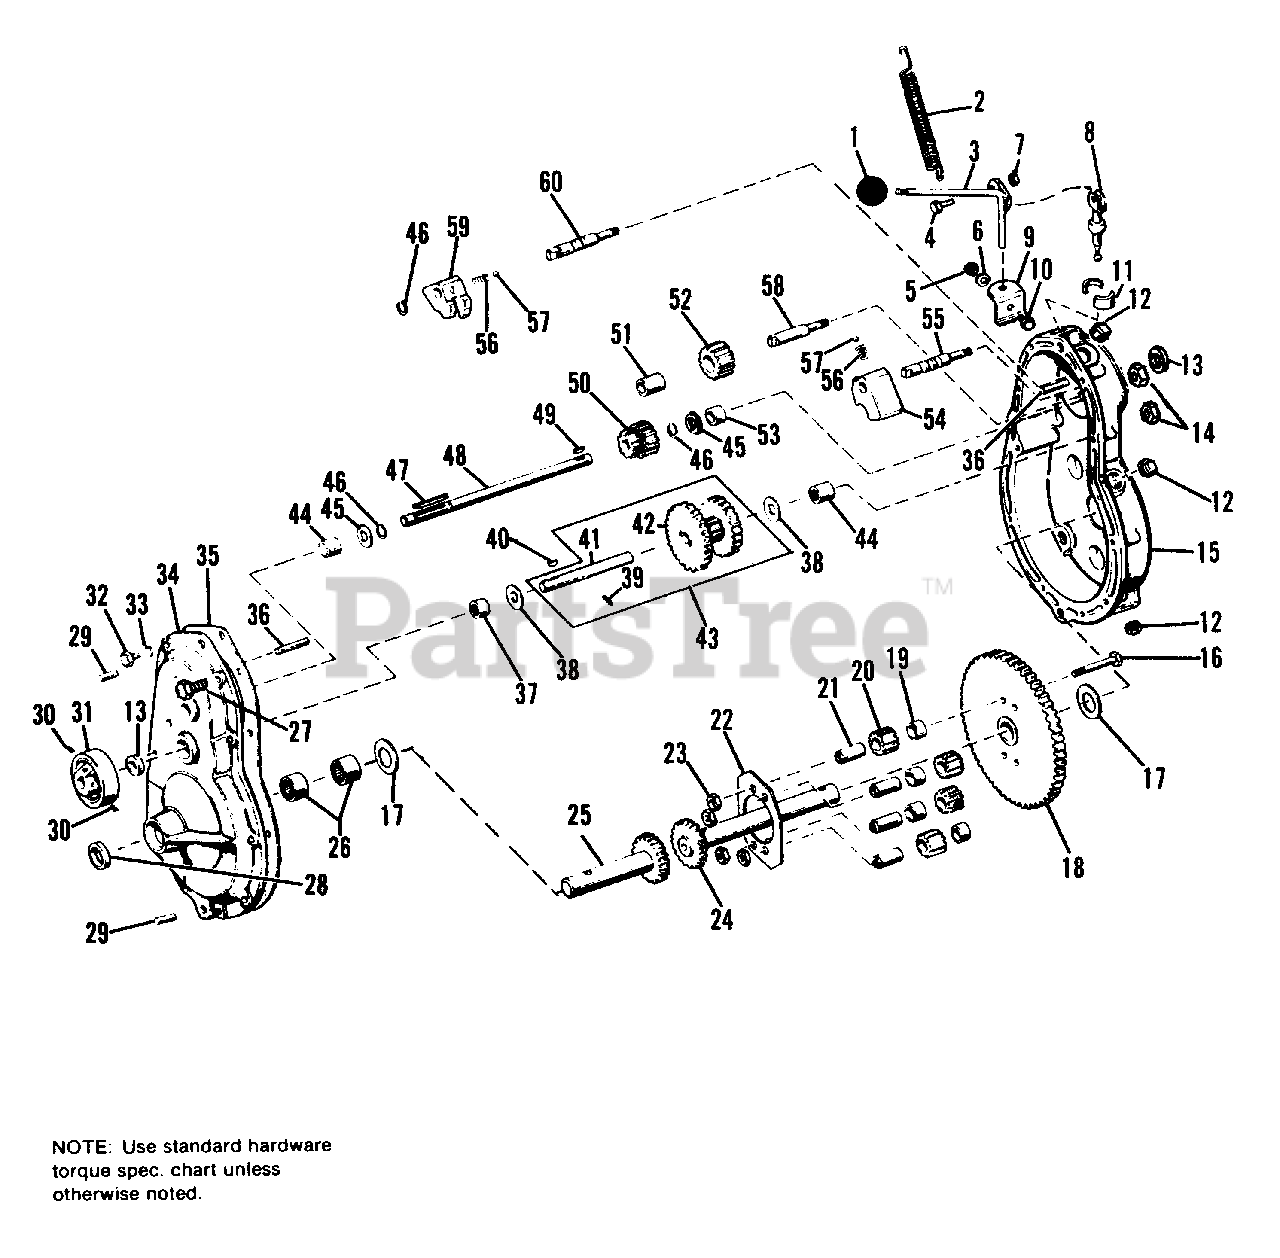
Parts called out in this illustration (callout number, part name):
2	SPRING
3	LEVER ASSY., Shift
4	CAPSCREW, Hex Hd., 1/4-20 x 3/4
5	NUT, Hex, Full, 5/16-18
6	LOCKWASHER, 5/16
7	LOCKNUT, Hex, 1/4-20
8	ROD ASSY., Shift
9	PIVOT, Shift Lever
10	CAPSCREW, Hex Hd., 5/16-18 x 7/8
11	BUSHING, Half
14	NUT, Hex, Full, 7/16-14
15	CASE ASSY., Gear
16	CAPSCREW, Hex Hd., 3/8-16 x 2-1/4
18	GEAR ASSY., Drive
19	SPACER, Diff.
20	PINION, Diff
21	SPINDLE, Diff
22	PLATE, Diff.
23	LOCKNUT, Hex, 3/8-16
24	SHAFT ASSY., Axle, R.H.
25	SHAFT ASSY., Axle, L.H.
26	BEARING, Roller
27	CAPSCREW, Hex Hd., 5/16-18 x 1-1/2
29	PIN, Roll, 3/8 x 1
30	SETSCREW. 5/16-18 x 5/16
31	DRUM, Brake
32	CAPSCREW, Hex Hd., 5/16-18 x 1-1/4
33	LOCKWASHER, 5/16
34	COVER, Gear Case
36	PIN ASSY., Roll
37	BEARING, Roller
39	PIN, Dowel
41	SHAFT. Brake
42	CLUSTER ASSY., Gear
43	CLUSTER GEAR & SHAFT ASSY.
44	BEARING, Roller
46	RING, Retaining
48	SHAFT, Pulley
49	KEY, Hi-Pro
50	PINION ASSY., Hi-Lo
51	BEARING, Roller
52	PINION, Reverse
53	BEARING, Roller
54	FORK, Shift. I & II
55	SHAFT, Shift, Hi-Lo
58	SHAFT. Pinion, Reverse
59	FORK, Shift. Reverse
60	SHAFT, Shift. Reverse
